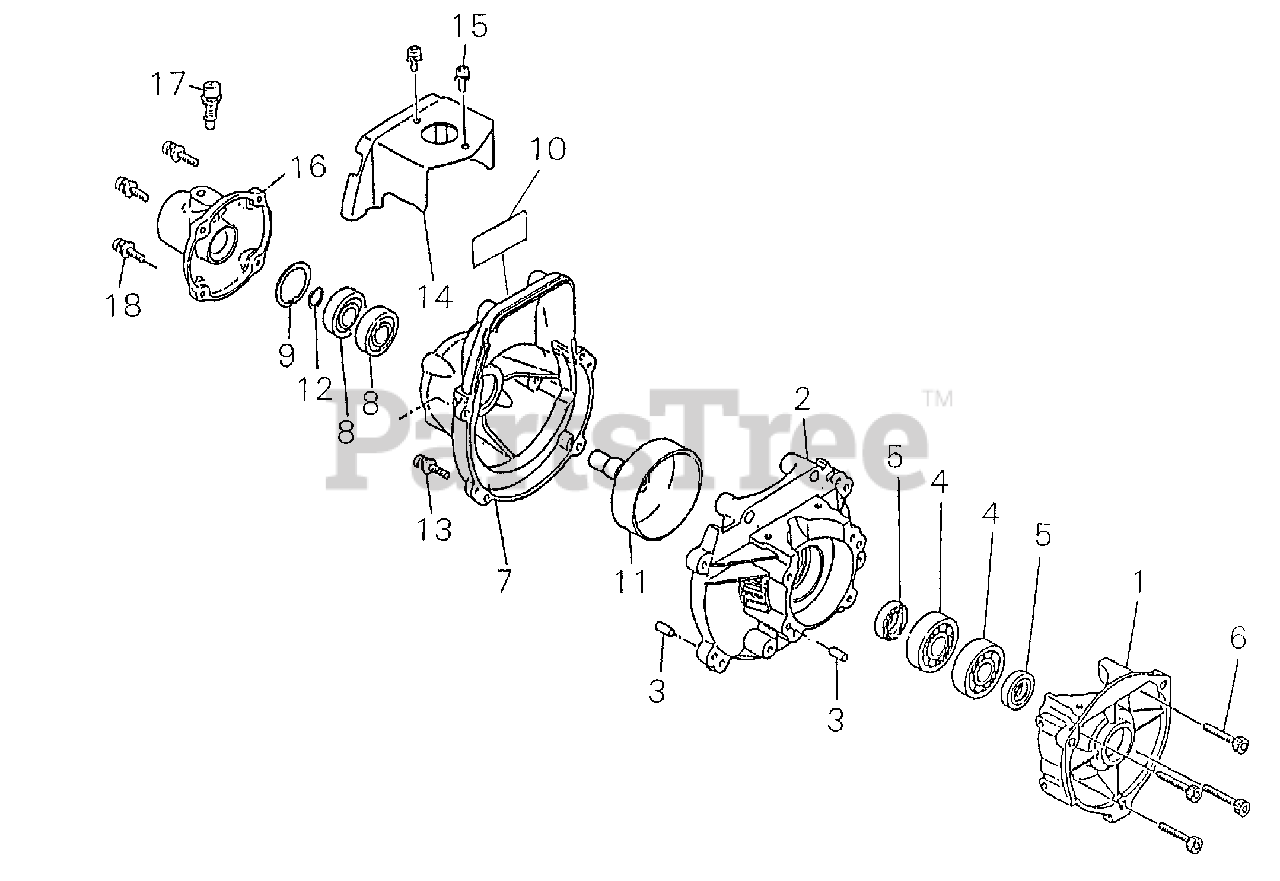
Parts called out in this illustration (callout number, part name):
1	CRANKCASE S
2	CRANKCASE M
3	PIN, LOCATING 5×10
4	BEARING, BALL 6201 C3
5	SEAL, OIL 12
6	BOLT 5×25
7	COVER, FAN
8	BEARING, BALL 6001 DDU
9	RING, SNAP Ø28
10	LABEL, TRADE
11	DRUM, CLUTCH
12	RING, SNAP Ø12
13	SCREW M5×20
14	COVER, ENGINE
15	SCREW M5×12
16	CUSHION, AV
17	PIN ASSY
18	BOLT M5×20
